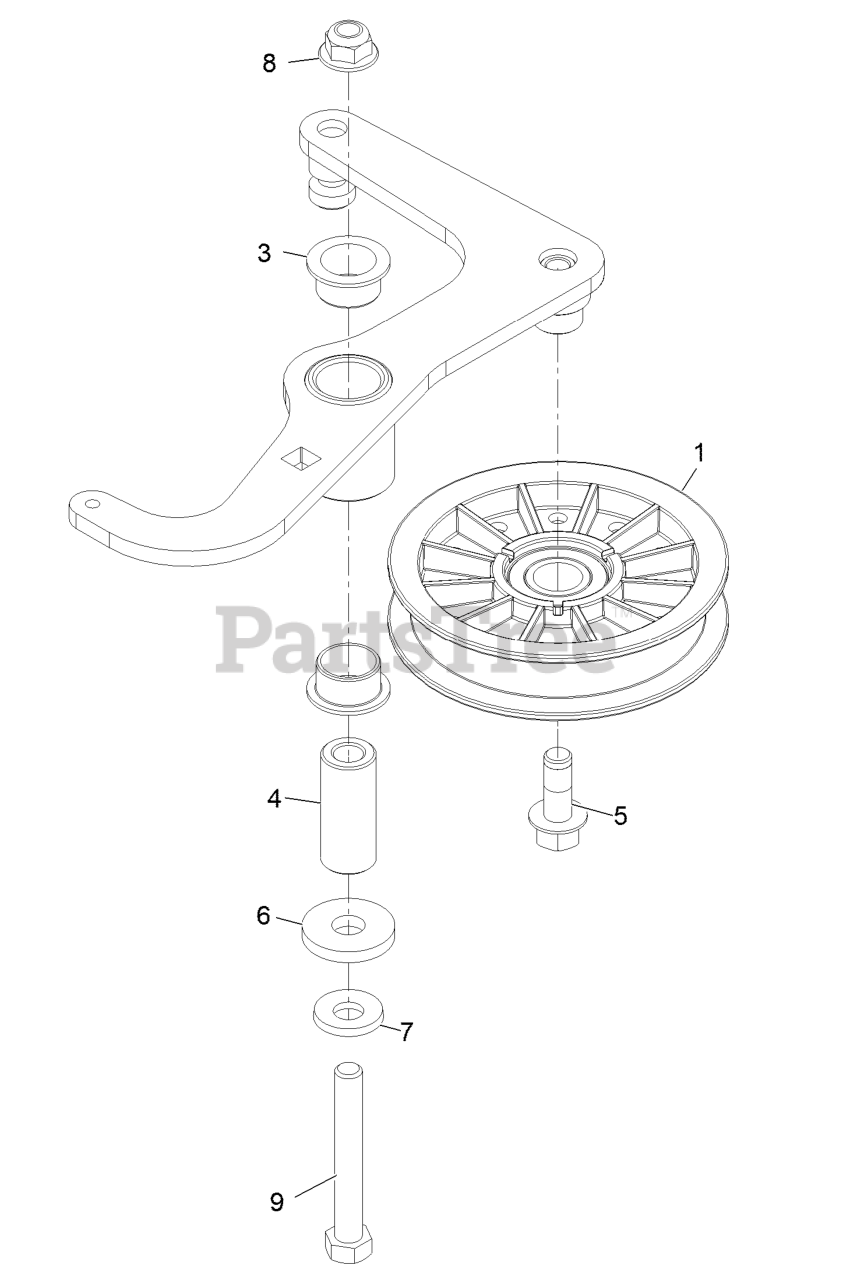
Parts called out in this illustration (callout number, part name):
1	Pulley-Idler, Flat
3	Bushing-Flanged
4	Spacer, Pivot
5	Screw-Hfh
7	Washer-Spring Disc 3/8
8	Nut-Nyloc 3/8-16 Flg
9	Screw-TAP
